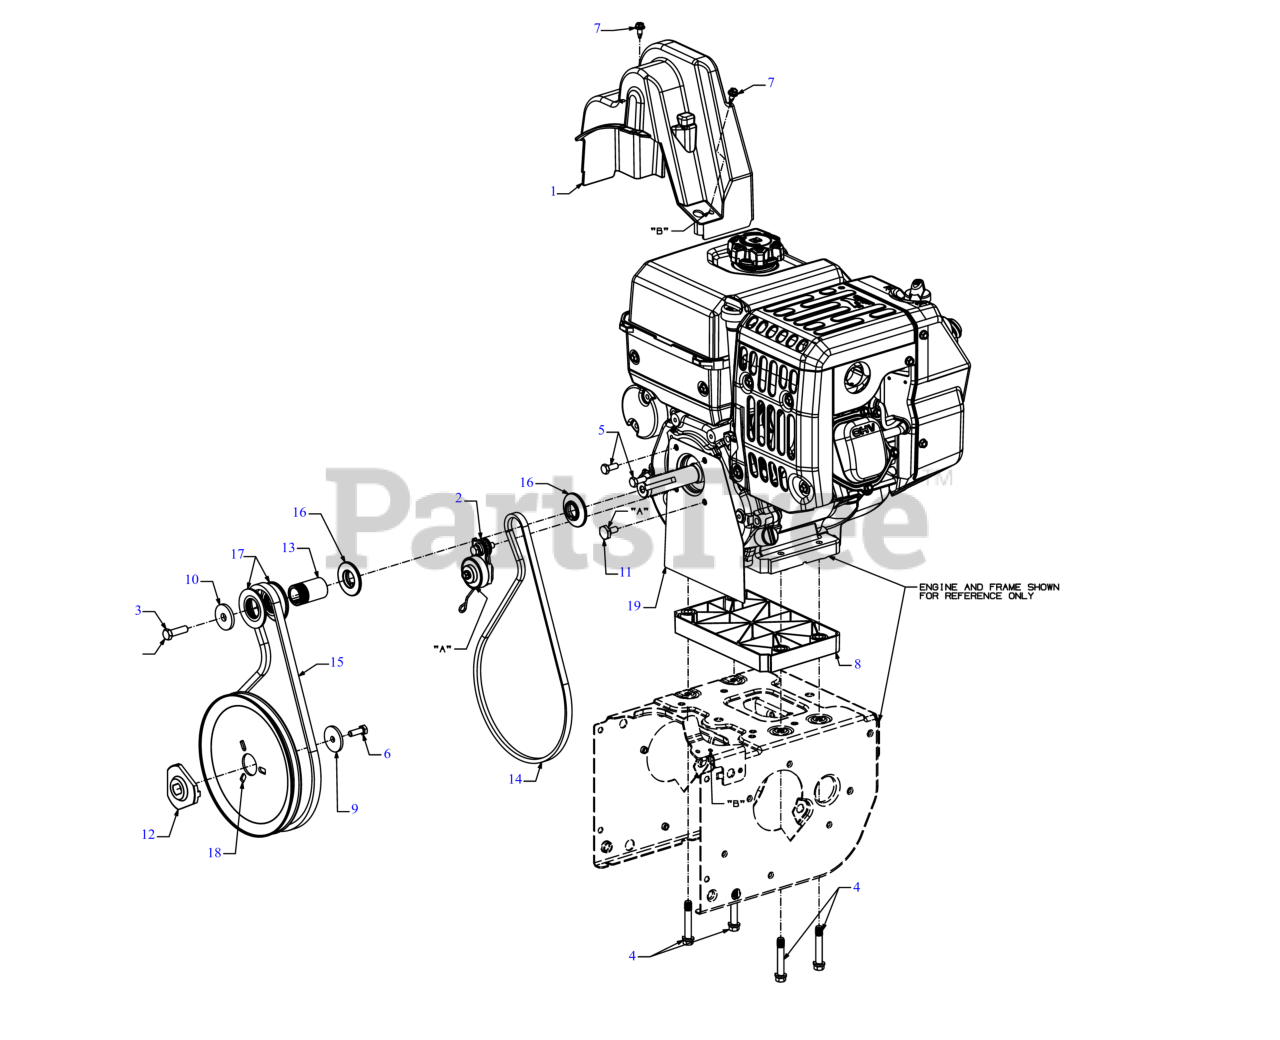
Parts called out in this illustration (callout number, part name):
1	BELT COVER ASSEMBLY
3	SCREW 3/8-24X1.25
4	SCREW 3/8-16 x 2.25
5	SCREW 5/16-24 x .750 GR5
6	SCREW 5/16-24 x .875 GR5
7	SCREW 1/4-20X.625
8	ENGINE MOUNTING SPACER
9	FLAT WASHER
10	FLAT WASHER .45 x 1.5 x .172 HT
11	SHOULDER SCREW
12	ADAPTER PULLEY .75 DIA W/DD
13	PULLEY SPACER
14	DRIVE BELT 3L x 36.90
15	AUGER BELT .500 x 37.74
16	HALF PULLEY-3/8 V x 1.7160
17	HALF PULLEY 4L-V x 2.40 OD
18	AUGER PULLEY 8.5 OD
19	ENGINE PLATE (FRONT)
